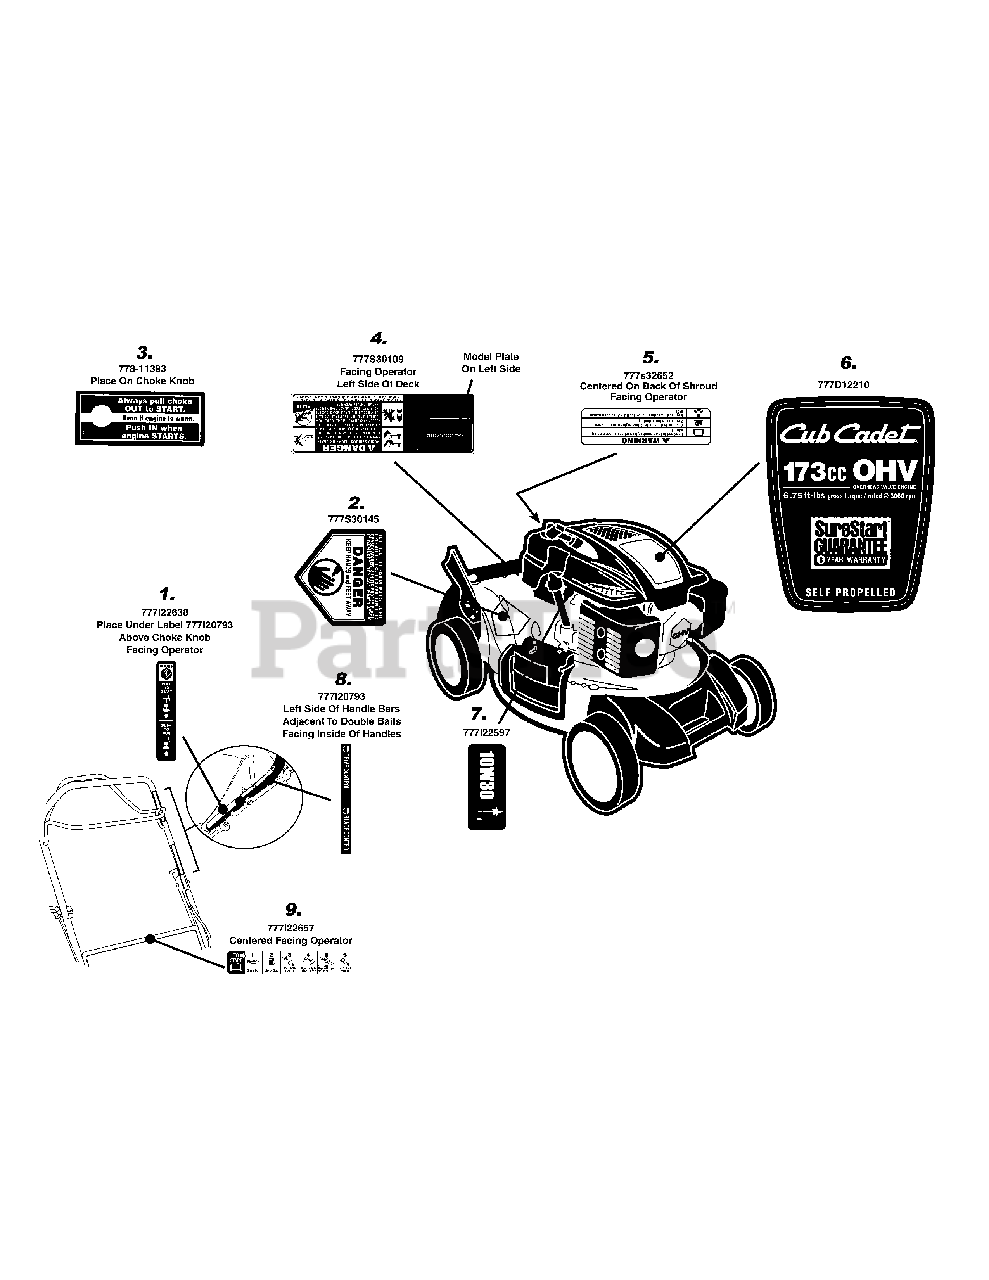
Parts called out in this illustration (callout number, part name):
1	LABEL-MOWER HANDLE:CHOKE START/RUN
2	LABEL
4	LABEL-MOWER DANGER
5	LABEL:MOWER:ENGINE SHROUD
6	LABEL-173CC SHROUD OHV SELF PROPEL
7	LABEL:MOWER SHROUD
8	LABEL-HANDLE
9	LABEL-MOWER HANDLE
